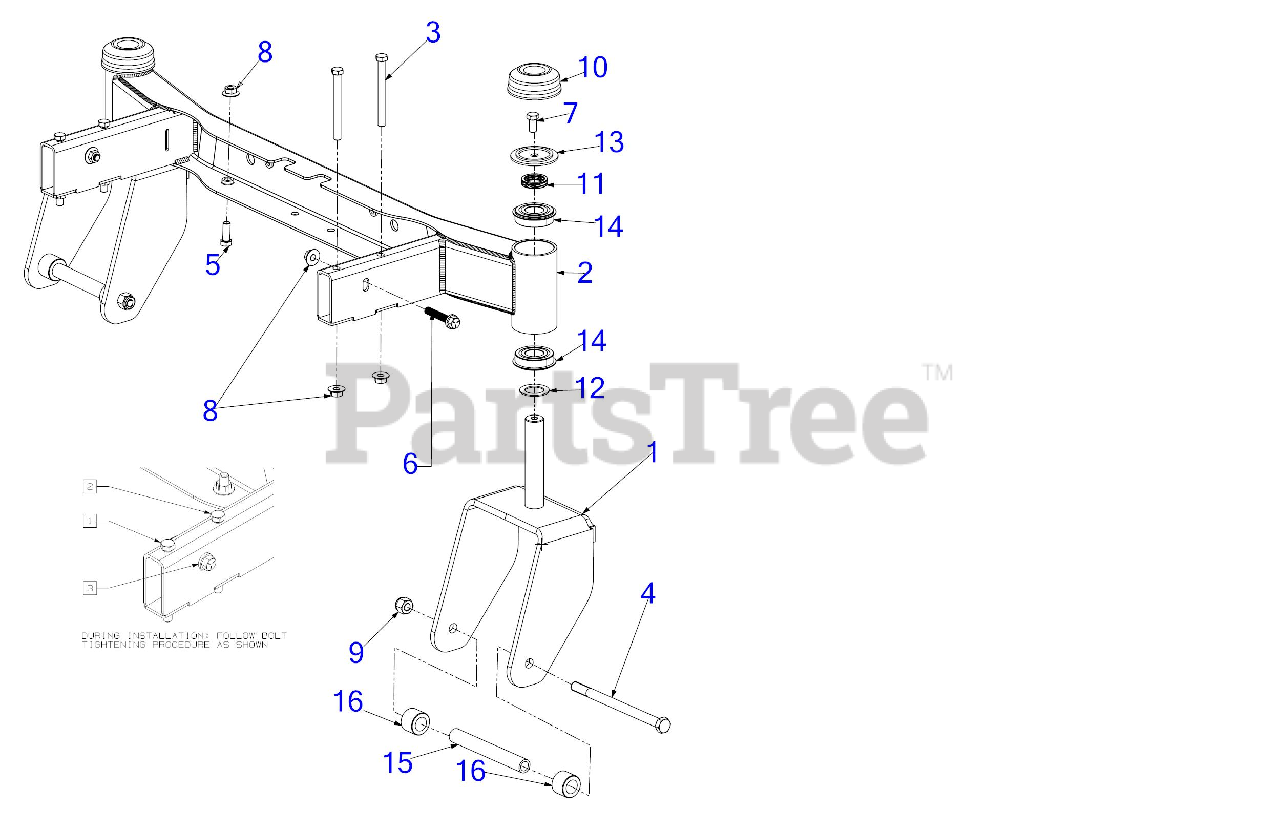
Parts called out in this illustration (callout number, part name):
3	SCREW 3/8-16 x 3.75 GR5
4	BOLT 1/2-20 x 7.25 GR5
5	SCREW 3/8-16 x 1 GR5
6	SCREW 3/8-16 x 2.00 GR5
7	SCREW 3/8-16 x .75 GR 5
8	FLANGE LOCK NUT
9	HEX NUT CENTER
10	CASTER AXLE CAP
11	WAVE WASHER
12	WASHER 1.010X1.560X.060
13	SHOULDER SPACER
14	BALL BEARING
15	CASTER SPACER
16	HUB:76 x 1.23X.92 LG
